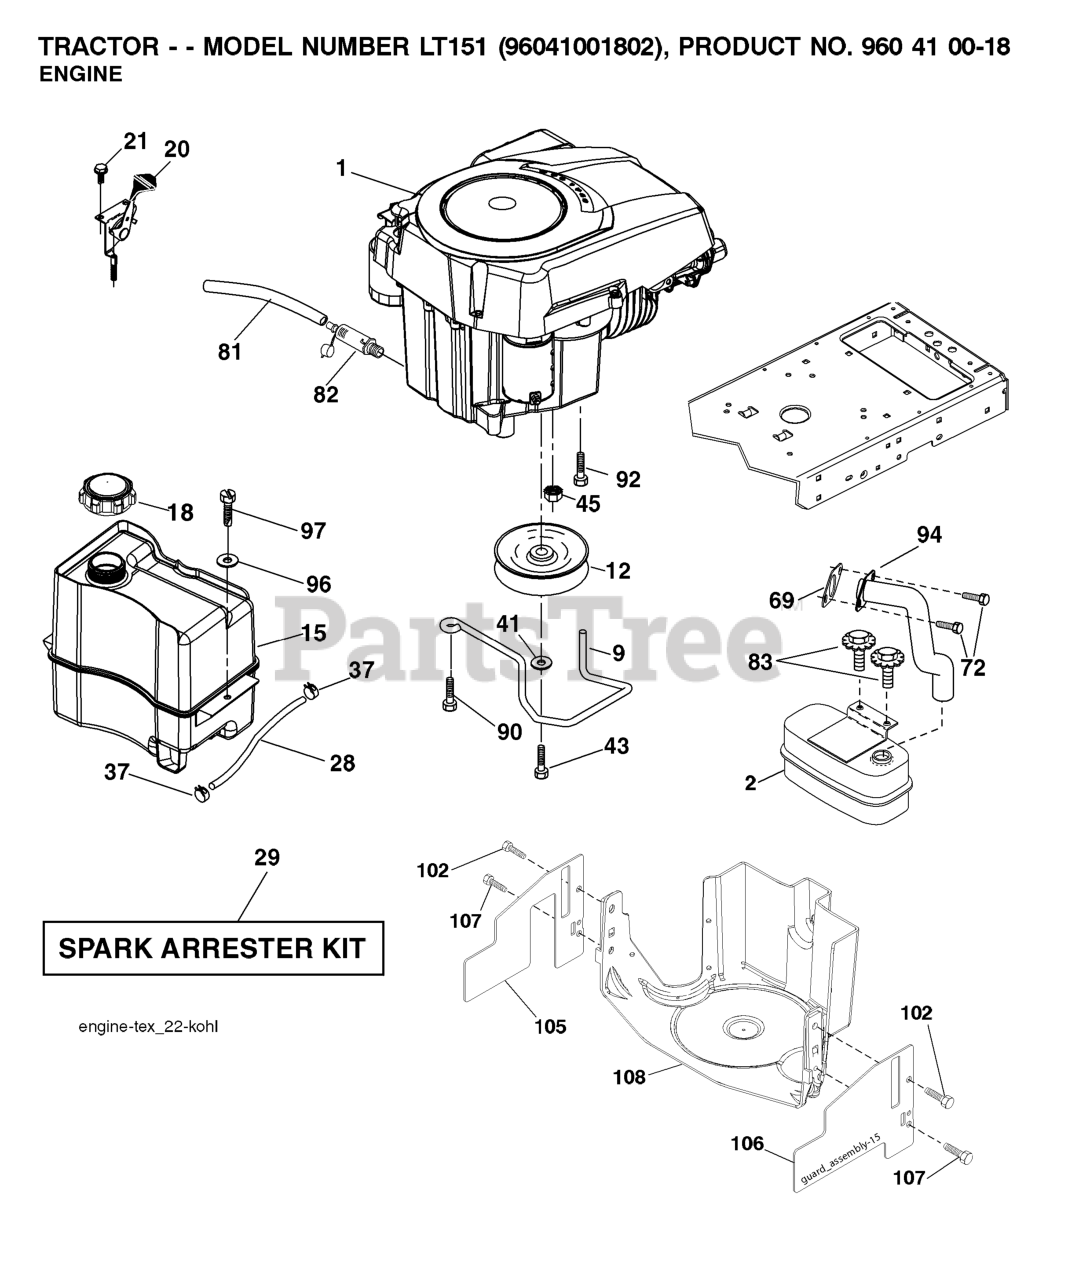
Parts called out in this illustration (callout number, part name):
2	MUFFLER.SINGLE.CYL.KOHL/B&S
9	KEEPER.BELT.ENGINE.3.25 (3 2)
12	PULLEY ENGINE
15	RP TANK FUEL FRT 1.5 GAL
18	FUEL CAP
20	CONTROL.TH/CK.C.
21	SCREW
28	LINE.FUEL.20
29	KIT.SPARK ARRESTOR 794945 B&S
37	HOSE CLAMP
41	LOCKWASHER
43	BOLT HEX 7/16-20X4-1/4"
45	NUT
69	GASKET.EXHAUST.KOHLER
72	SCREW.SOCKET HD.5/16-1
81	TUBE, DRAIN OIL ASM.
82	PLUG DRAIN OIL EASY
83	BOLT.5/16-18UNCX3/4 W/SEMS.BLK
90	SCREW 3/8-16X1
92	SCREW 3/8-16X1
94	RP.TUBE.EXHAUST.KOHL.COURAGE
102	SCREW
105	SHIELD.SIDE.LH.3842"TEX FRENCH
106	SHIELD.SIDE.RH.3842"TEX FRENCH
107	SCREW.1/4-20X5/8
